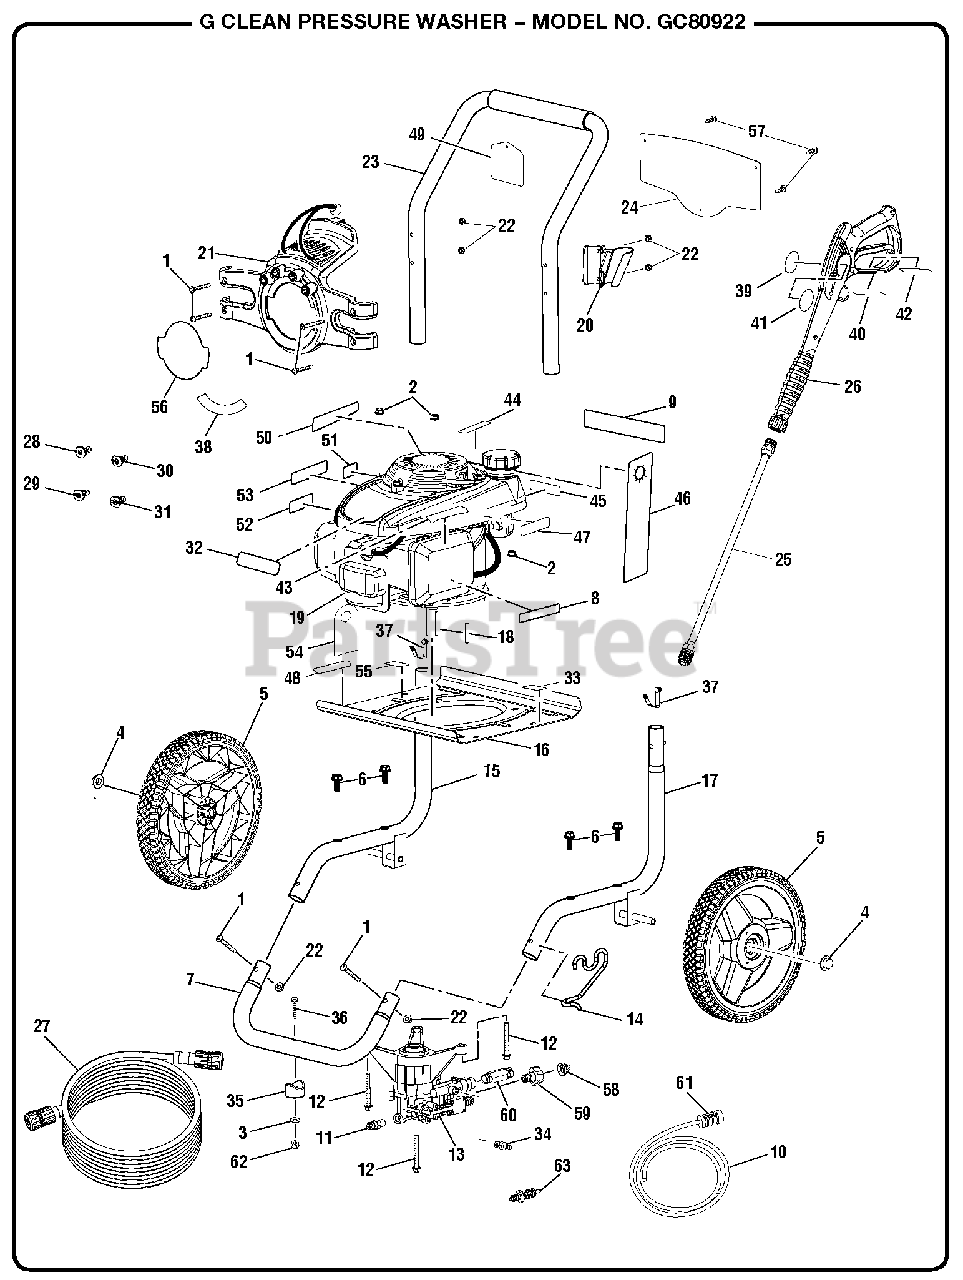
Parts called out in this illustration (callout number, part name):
1	Screw (M6 x 48 mm,T30 Torx Pan Hd.)
2	Flange Nut (M8 x 1.25 in.)
3	Washer (1/4 in.)
6	Bolt (M6 x 16 mm)
7	Front Frame Assembly
8	EMC Label
9	Danger Label
10	Chemical Siphon Tube
11	Thermal Release Valve
12	Bolt (M8 x 60 mm, Flange Hd.)
13	Pump
14	Wand Holder Loop
15	Main Frame Assembly RH
16	Engine Plate
17	Main Frame Assembly LH
18	Output Shaft Key (40 mm)
19	Engine (Honda)
20	Wand Holder
21	Hose and Nozzle Assembly
22	Lock Nut (M6)
23	Handle w/Foam
24	Quick Start Panel
25	Spray Wand
26	Trigger Handle Assembly
27	Hose (25 ft.)
28	Soap Nozzle
29	25deg Nozzle
30	40deg Nozzle
31	0deg Nozzle
32	Honda Label
33	Warning Label
34	Detergent Suction Kit
36	Screw (1/4-20 x 1.85 in., T30 Torx Hd.)
37	Spring Clip
38	Performance Label
39	Label (Wand Logo)
40	Sp Label (Wand Warning)
41	Label (Wand Warning)
42	Label (Wand Rating)
43	Inquiries Label
44	E85 Label
45	Do Not Mix Label
46	Warning Hangtag
47	Engine Start Label
48	Data Label
49	Nozzle Hangtag
50	Release Water Label
51	Lubricant Label
52	Hot Surface Label
53	Combustion Label
54	Oil Cap Hangtag
55	Oil Fill Location Label
56	Performance Label
57	Screw (M3 x 5 in.)
58	Filter Screen
59	Outlet Tube
60	Inlet Tube
61	Chemical Siphon Filter
62	Lock Nut (1/4-20)
63	Unloader Valve
